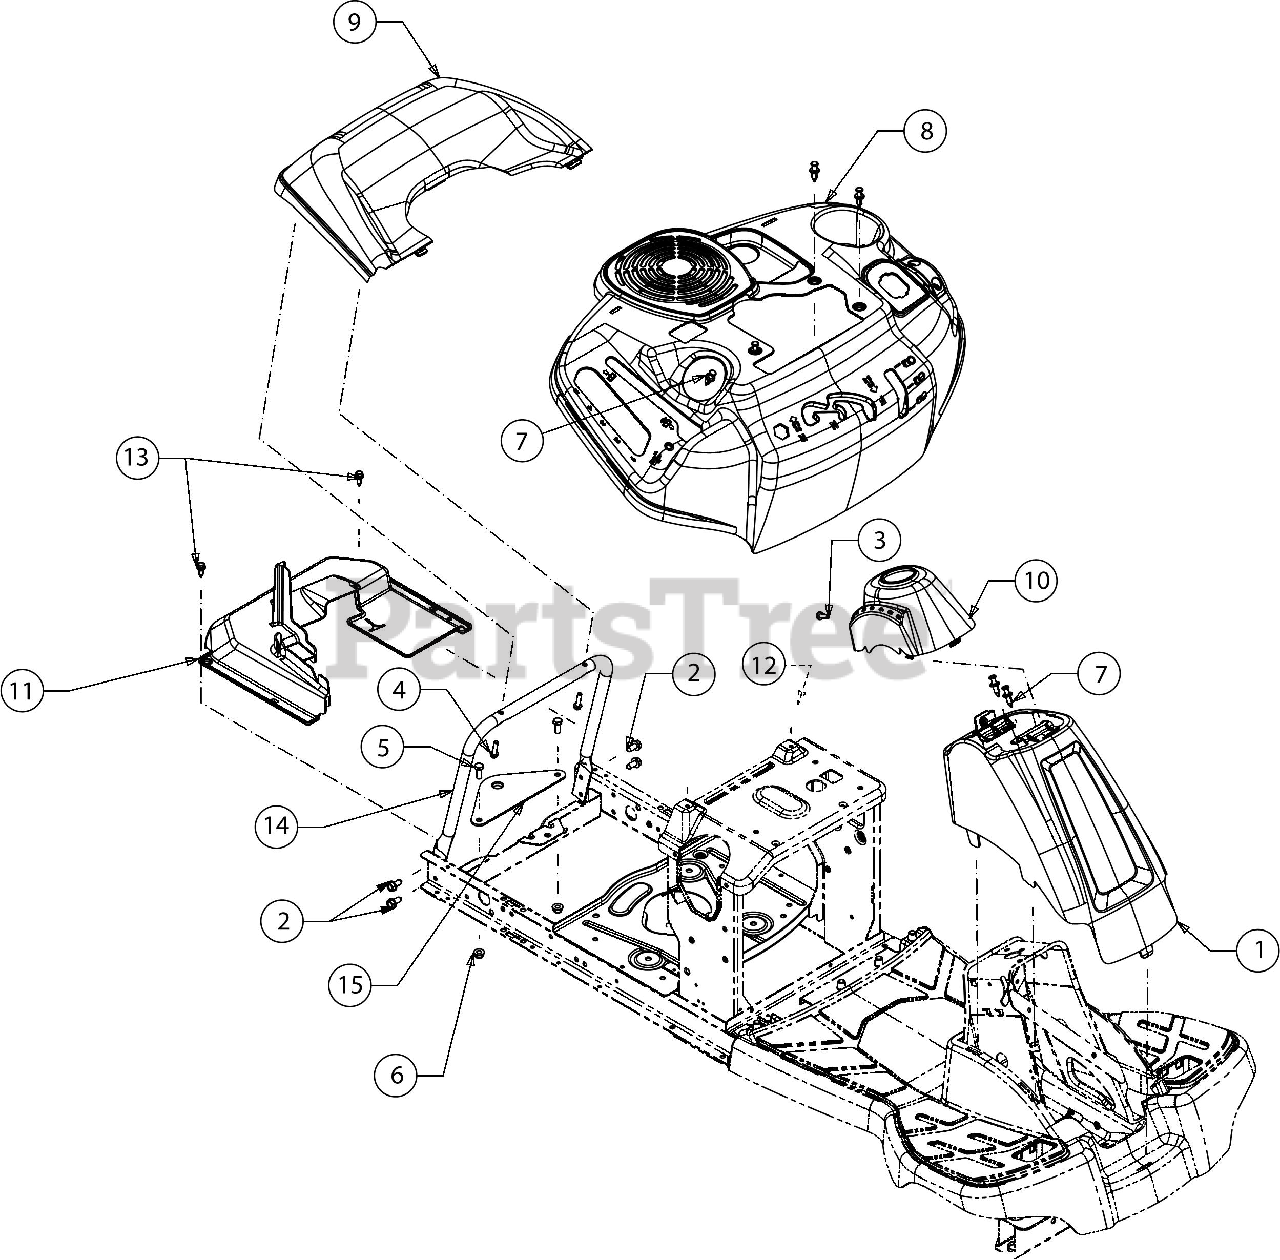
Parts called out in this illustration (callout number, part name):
1	COLUMN COVER ASSEMBLY
2	SCREW 5/16-18 x .750
3	SCREW 1/4-20X.75
4	SCREW 1/4-15 x 1.00
5	SCREW 5/16-18 x .75 GR5
6	FLANGE LOCK NUT 5/16-18
7	PLASTIC RIVET
8	FENDER
9	REAR COVER
10	STEERING COLUMN CAP (SEARS RED)
11	DRIVE OVER REAR
12	BUMPER .62 DIA x .50
13	SHOULDER SCREW
14	REAR SUPPORT TUBE
15	HITCH PLATE
